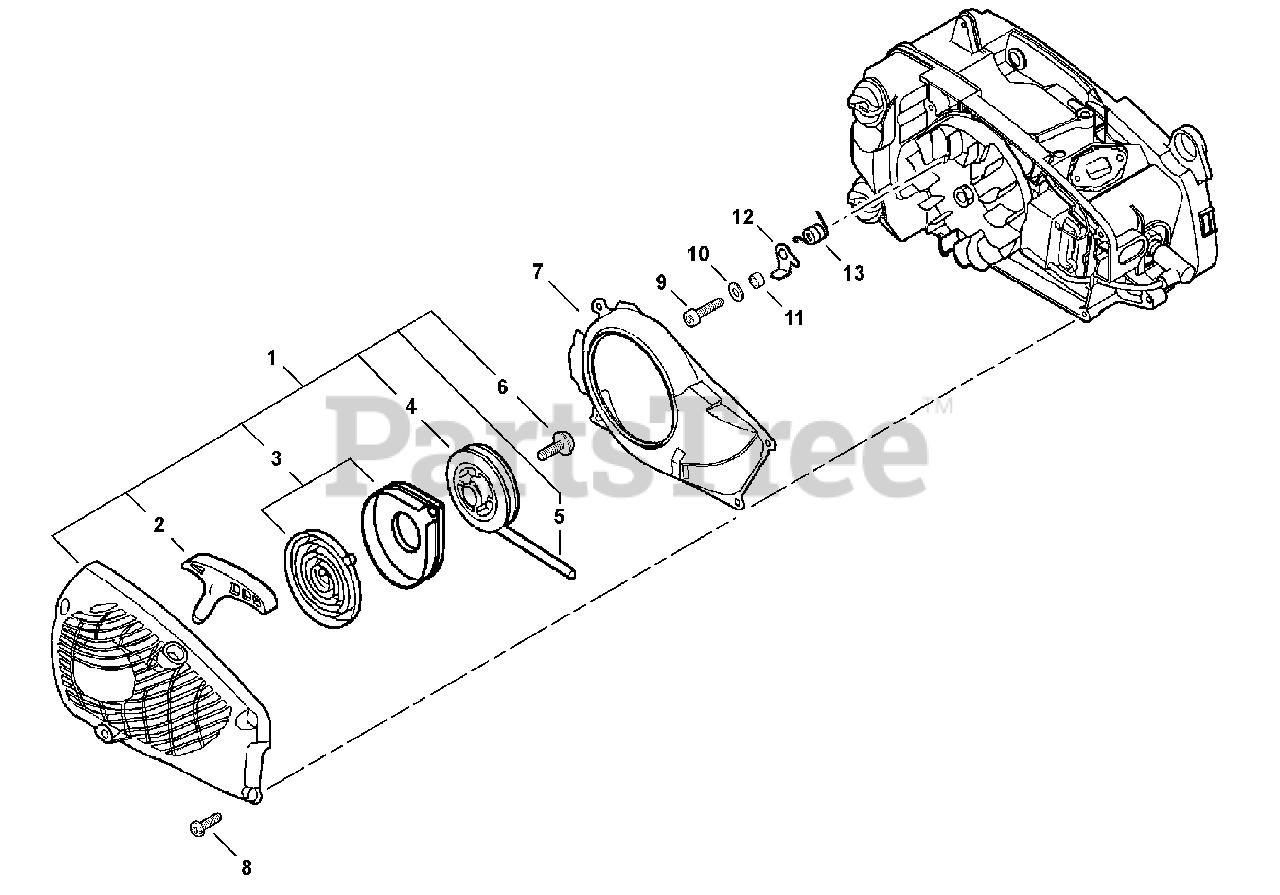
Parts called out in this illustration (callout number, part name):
1	STARTER ASSY, RECOIL
2	GRIP, STARTER
3	SPRING SET, RECOIL
4	REEL, ROPE
5	ROPE, STARTER
6	SCREW
7	COVER, FAN
9	BOLT 5×14
10	WASHER 5.5×12×0.8
11	SPACER 5.2×8×2.1
13	SPRING, TORSION
